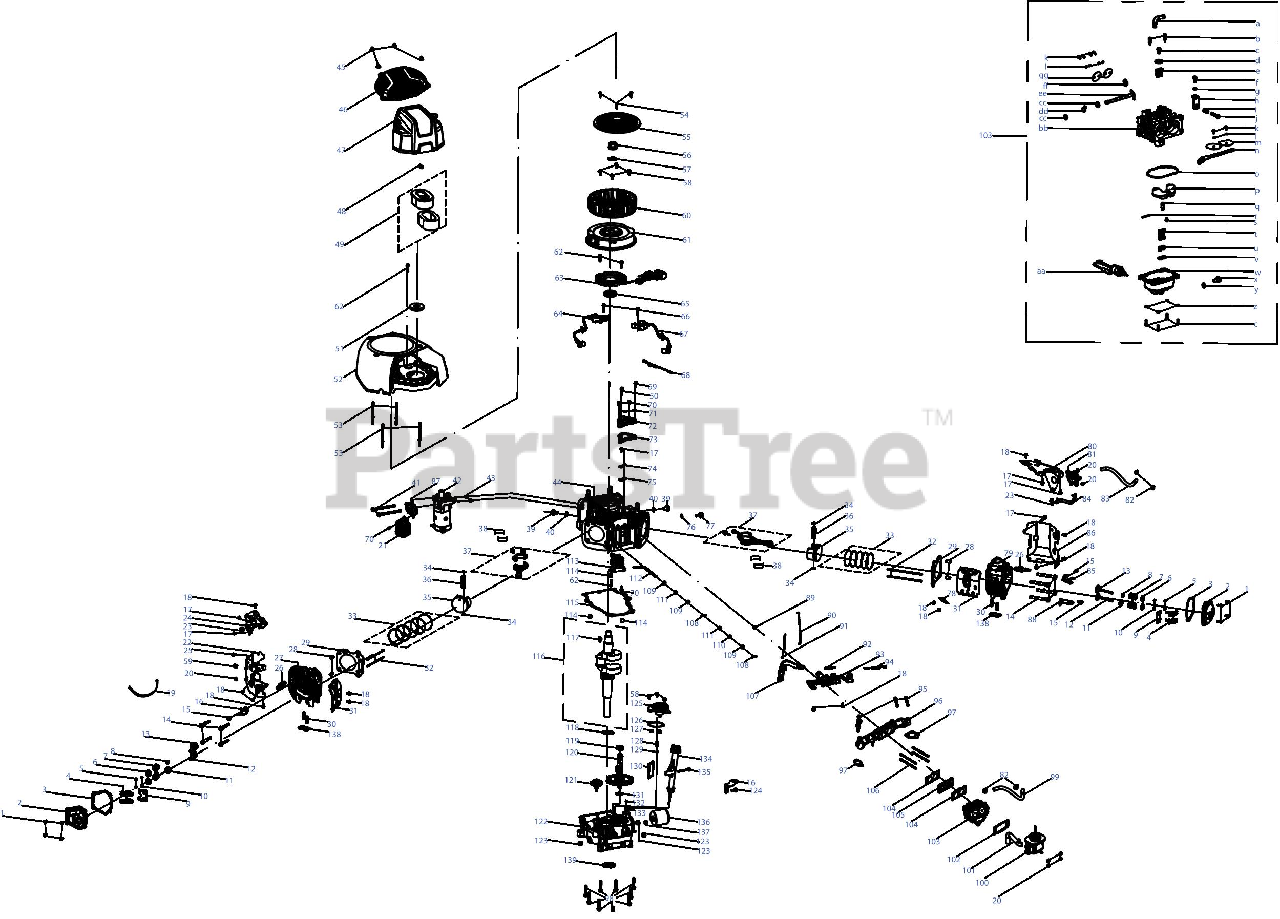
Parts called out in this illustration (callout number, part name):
1	Bolt, M6x22
2	Valve Cover
3	Gasket, Valve Cover
4	Rocker Arm Assembly
5	Valve Adjust Cap, Exhaust
6	Valve Spring Seat
7	Valve Spring
8	Intake Valve Seal
9	Rocker Arm Base
10	Valve Locker
11	Valve Spring Seat
12	Exhaust Valve
13	Intake Vavle
14	Bolt, M10x1.25x87
15	Bolt, M8x16
16	Lift Hook
17	Bolt, M6x10
18	Bolt, M6x12
19	Tape, L=150mm
20	Nut, M6
21	Regulator Assembly
22	Cylinder Head Baffle
23	Spray Head Washer
24	Guard, Right
25	Bolt, M6x10
26	Spark Plug
27	Cylinder Head
28	Pin, 12x20
29	Gasket, Cylinder Head
30	Stud, M8x34
31	shroud
32	Push Rod
33	Piston Ring Set
34	Circlip
35	Piston
36	Piston Pin
37	Connecting Rod Assembly
38	Connecting Rod Bearing
39	Earth Bolt
40	Washer, 14x1.5x22
41	Bolt, M8x110
42	Electric Starter
43	Pin,10x12
44	Crankcase
45	Nut,M6
46	Fix Shroud
47	Air Filter Cover Assembly
48	Butterfly Nut
49	Air Filter Element
50	Bolt, M6x28
51	Ring,Air Filter
52	Blower Housing
54	Self-tappling Screw, ST5.5x25
55	Shroud
56	Nut, M20x1.5
57	Washer, 20.5x5x40
58	Bolt, M6x18
60	Cooling Fan
61	Flywheel
62	Bolt, M6x25
63	Charging Coil
64	Ignition Module
65	Oil Seal, 38x58x8
66	Bolt, M6x30
67	Ignition Module
68	Cable Assembly
69	Bolt, M6x22
70	Bolt, M6x16
71	Wire Board
72	Breather Cover
73	Gasket, Breather Cover
74	Oil Block
75	Breather Valve
76	Washer, 10.5x1.5x18
77	Bolt, M10x1x10
79	Cylinder Head
80	Shroud, Left
81	Fuel Pump
82	Clamp
83	Fuel Hose, 6.3x12.5x110
84	Fuel Hose
85	Fuel pipe bracket
86	Cylinder Head Baffle
87	Starter Relay Support
88	Lift Hook
89	Choke Linkage Lock Clamp
90	Throttle Linkage
91	Choke Lever
92	Governor Spring
93	Governor Gear Bracket Assembly
94	Governor Spring
95	Bolt, M8x50
96	Intake Manifold
97	Gasket, Intake Manifold
98	Bolt, M8x48
99	Fuel Hose, 6.3x12.5x470
100	Intake Manifold
101	BREATHER HOSE
102	Gasket, Air Filter
103	Carburetor
104	Gasket, Carburetor
105	Insulator
106	Stud, M6x105
107	Governor Lever
108	Cotter Pin
109	Washer, 8.5x2x15.8
110	Oil Seal, 8x14x4
111	Bearing, HK081210
112	Governor Gear Shaft
113	Lower Rocker Arm
114	Pin, 8x12
115	Gasket, Crankcase
116	Crankshaft
117	Woodruff Key
118	Washer, 38.5x1x54
119	Bearing, 6003
120	Camshaft
121	Governor Gear
122	Crankcase Cover
123	Earth Bolt
124	Bolt, M8x20
125	Oil Pump
126	Gasket, Oil Pump
127	Pin, 8x8
128	Oil Pump Spring
129	Steel Ball, 9.5
130	Filter Screw
131	Washer, 17.4x1x25.9
132	O-Ring, 13.2x2.65
133	Pin, 14x10x12.5
134	Dipstick
135	Bolt, M6x55
136	Oil Filter
137	Connection Pipe
138	Gasket, Muffler
139	Oil Seal, 38x58x8
